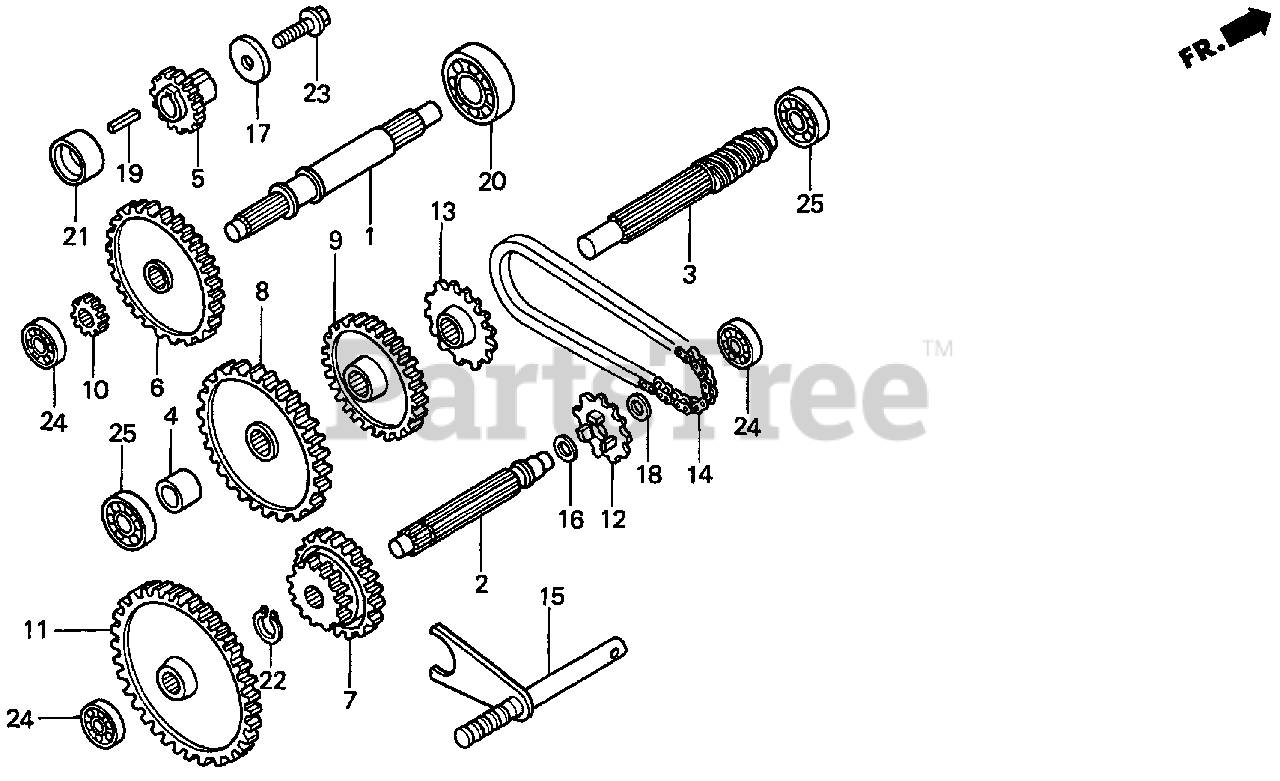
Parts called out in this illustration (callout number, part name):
1	SHAFT, INPUT
2	COUNTERSHAFT
3	SHAFT, FINAL
4	COLLAR A, DISTANCE
5	GEAR, INPUT SHAFT (25T)
6	GEAR, COUNTERSHAFT (59T)
7	GEAR, CHANGE (31T)
8	GEAR, COUNTERSHAFT FIRST (51T)
9	GEAR, COUNTERSHAFT SECOND (37T)
10	GEAR, IDLE DRIVE (18T)
11	GEAR, IDLE DRIVEN (67T)
12	SPROCKET, REVERSE DRIVE
13	SPROCKET, REVERSE DRIVEN
14	CHAIN, REVERSE (RK35X30LE)
14	CHAIN, REVERSE (35X30)
15	SHAFT, GEARSHIFT FORK
16	WASHER, THRUST (15MM)
17	WASHER, SPECIAL (28X8.5X4.0)
18	WASHER, THRUST (12MM)
19	KEY (5X5X33)
20	BEARING, RADIAL BALL (6022)
21	COLLAR, INPUT SHAFT GEAR
22	CIRCLIP (OUTER) (15MM)
23	BOLT, FLANGE (8X25)
24	BEARING, RADIAL BALL (6201)
25	BEARING, RADIAL BALL (6202)
